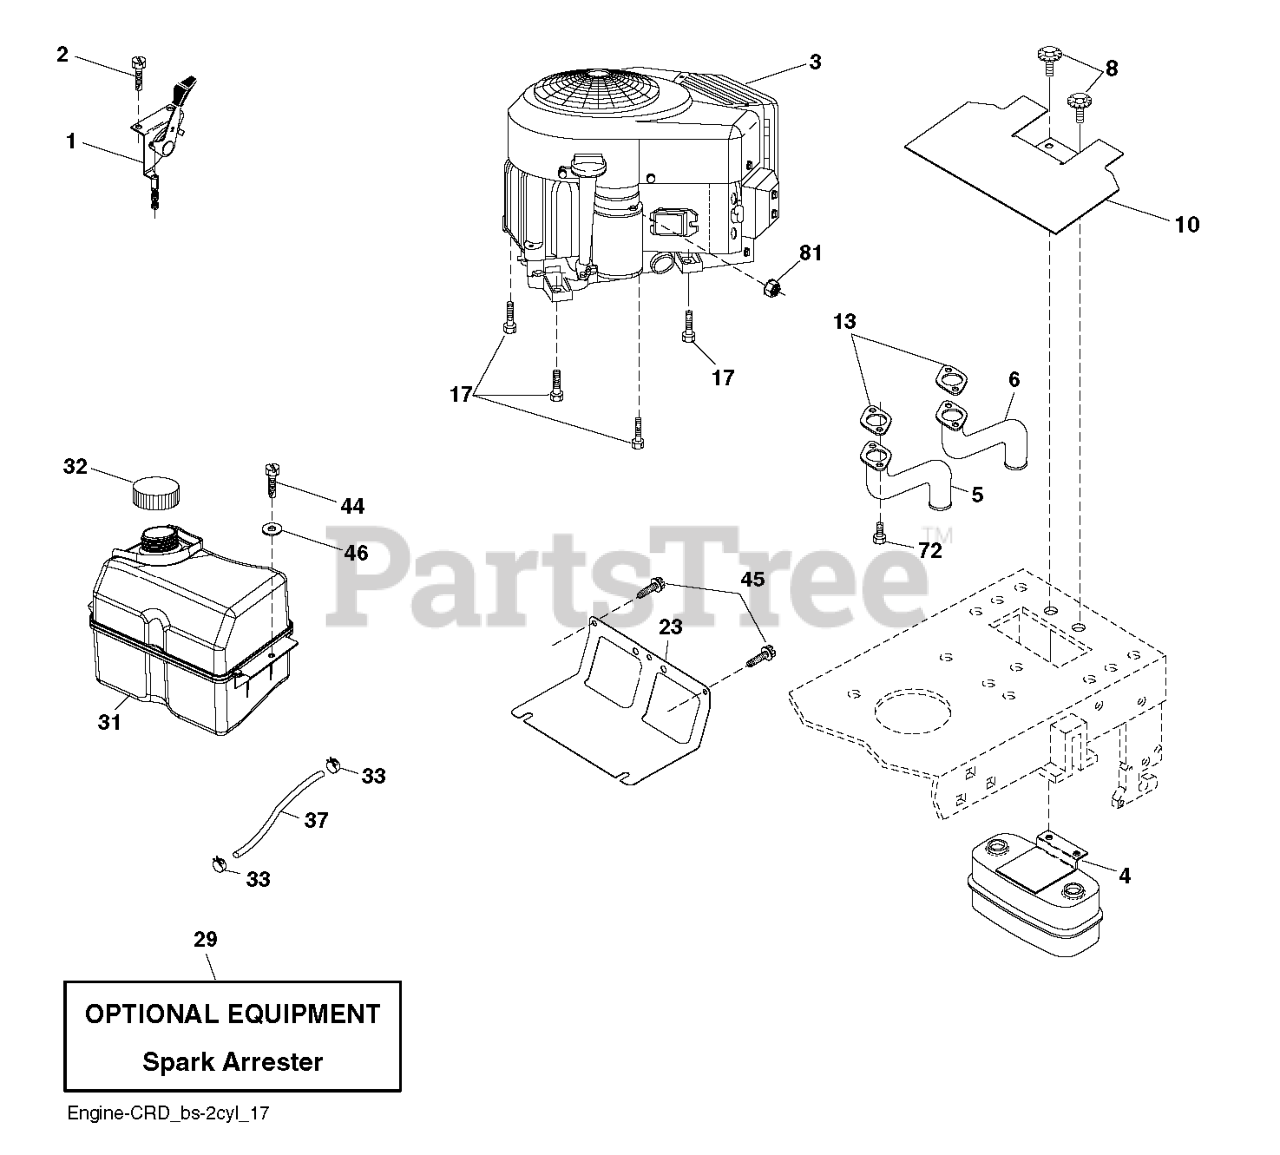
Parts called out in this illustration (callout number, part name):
1	CONTROL.TH/CK.COBRA.B&S.TWN.BK
2	SCREW.#10 X 0.750.BOS
4	MUFFLER.TWIN.CYL.LOW.TONE
5	EXHAUST.TUBE.LH.BS/TWIN
6	EXHAUST.TUBE.RH.B&S.TWIN.INTEK
8	BOLT.5/16-18UNCX3/4 W/SEMS.BLK
10	SHIELD.HEAT.MUFFLER
13	GASKET.MUFFLER
17	SCREW.3/8-16
23	SHIELD.BROWNING.PNT.GT.V2
29	KIT.SPARK ARRESTOR 794945 B&S
31	TANK.ASM.FUEL.FR.2.5GA.
32	CAP ASM.FUEL.2.25"FR.
33	HOSE CLAMP
37	LINE.FUEL.20
44	SCREW HEXWSHR 1/4-20X3/4
45	SCREW, 3/8-16X3/4
72	SCREW.SOCKET.HEAD.5/16-18
81	NUT
